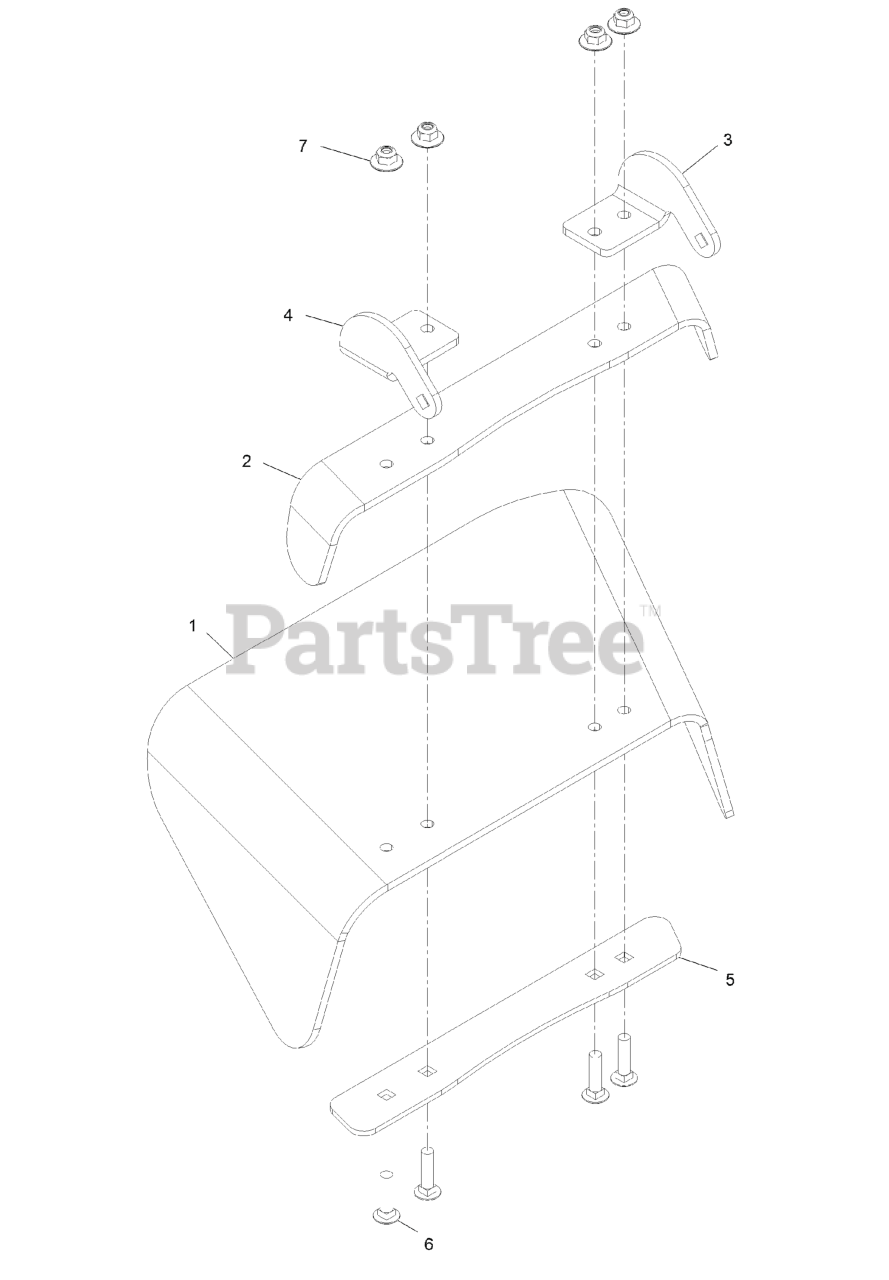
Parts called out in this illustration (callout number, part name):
1	DEFLECTOR-RUBBER
2	BRACKET-TOP DEFLECTOR
3	BRACKET-DEFLECTOR
4	BRACKET-DEFLECTOR
5	STRAP-BOTTOM DEFLECTOR
6	SCREW-CARR
7	Nut-Nyloc 3/8-16 Flg
